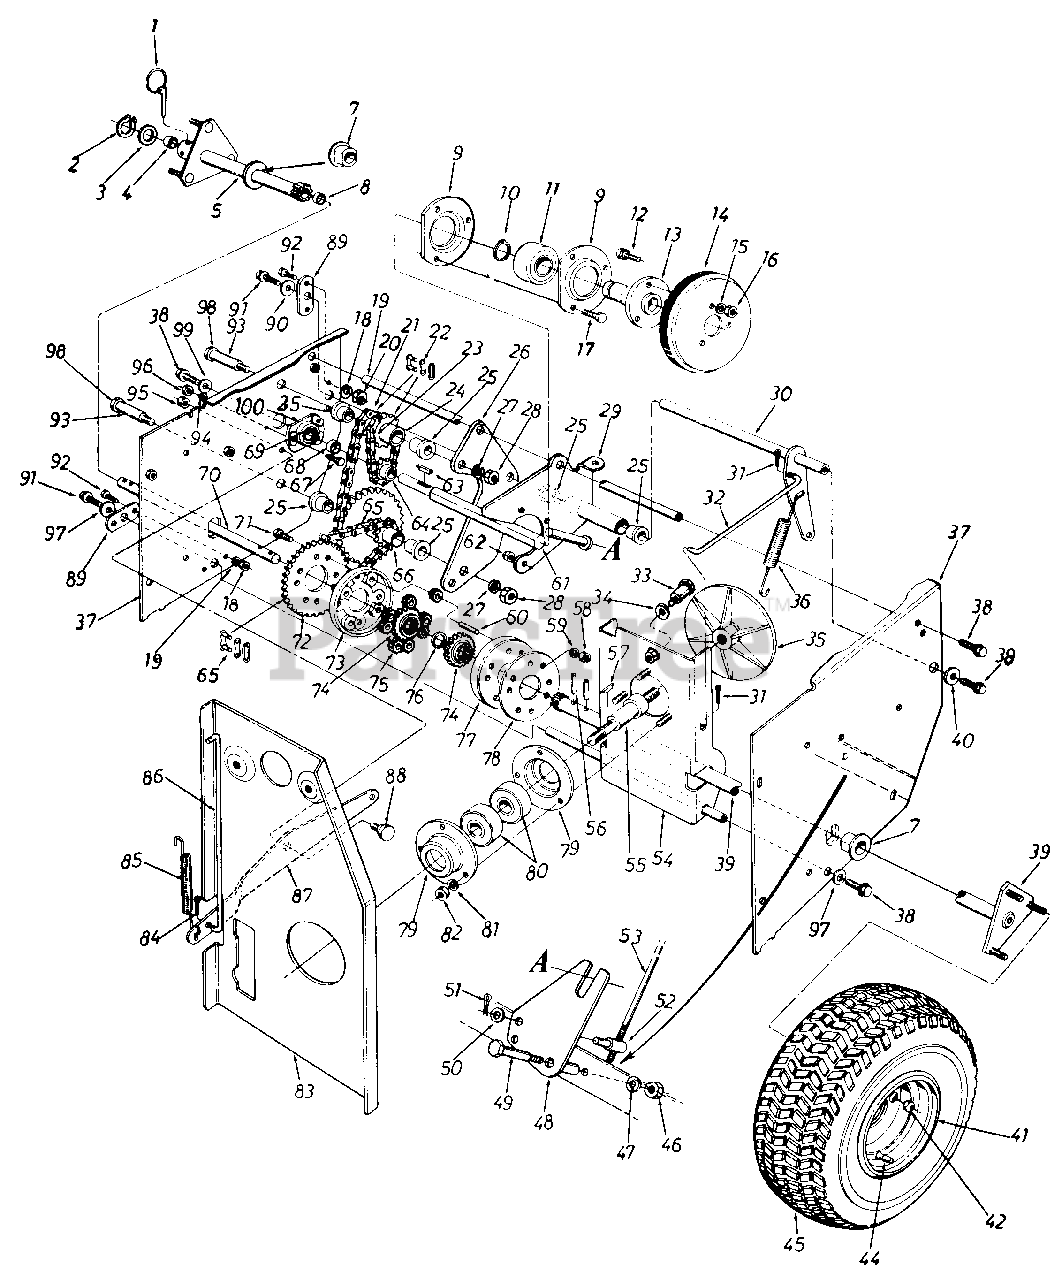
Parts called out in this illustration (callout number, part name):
1	Klick Pin 1/4 Dia. x 1.75
2	Snap Ring .625" Shaft
3	Fl-Wash. .62" I.D. x 1.25"
4	Sleeve Brg.
5	Differential Tubing Ass'y.
7	Flange Brg. w/Flats 1" I.D.
8	Sleeve Brg.
9	Bearing Housing
10	Snap Ring 1.00" Dia.
11	Ball Brg. .25MM x 52MM x 15MM Thk.
12	Hex Sems Bolt 5/16-18 x . 75 " Lg .
13	Friction Wheel Adapter
14	Friction Wheel Ass'y.
15	L-Wash. 5/16" I.D.
16	Hex Nut 5/16-18 Thd.
17	Hex Bolt 1/4-28 x .62" Lg.
18	L-Wash. 1/4" I.D.
19	Sliding Support Axle
20	Hex Nut 1/4-20 Thd.
21	#41 Chain 1/2" Pitch x 43 Links
22	Master Link
23	#41 Chain 1/2" Pitch x 19 Links
24	and 14 Teeth Sprocket Hub Ass'y.
25	Flange Brg. .630" I.D.
28	Hex L-Jam Nut 3/8-24 Thd.
29	Sliding Brkt. Ass'y.
30	Drive Clutch Brkt. Ass'y.
31	Inter. Cot. Pin 5/16" Dia.
32	Drive Clutch Rod 7.38" Lg.
33	Shld. Bolt
34	Bell-Wash. .44" I.D. x .88"
35	Aluminum Drive Plate
36	Extension Spring 4.31" Lg.
37	Frame Ass'y.
38	Hex L-Bolt 5/16-18 x .62"
39	Differential Shaft Ass'y.
40	Fl-Wash. .345" I.D. x .75"
41	Rim Only 16"
42	Cone Nut 3/8-24 Thd.
44	Tubeless Air Valve
45	Wheel Ass'y. Comp. 16 x 6.5
46	Jam Nut 3/8-16 Thd.
47	L-Wash. 3/8" I.D.
50	Fl-Wash. .344" I.D. x .62"
51	Cotter Pin 3/32" Dia. x .75"
52	Adjustment Ferrule
53	Shifting Rod
56	H-Spring Pin Spiral 3/16" Dia. x 1.25" Lg.
57	#61 Hi-Pro Key 3/16 x 5/8" Dia.
58	Hex Nut 1/4-28 Thd.
59	L-Wash. 1/4" I.D.
60	Differential Pin
61	Hex Shaft
62	Hex L-Nut 1/4-28 Thd.
63	#9 Hi-Pro Key 3/32 x 5/8" Dia.
64	8 Teeth Sprocket
65	#420 Chain .50 Pitch x 37 Links
66	9 and 32 Teeth Sprocket Hub Ass'y.
67	Hex Bolt 1/4-20 x .62" Lg.
68	Spacer .51" I.D. x .69" O.D.
69	Ball Bearing
70	Differential Connecting Shaft
71	Hex Bolt 1/4-28 x 1.75" Lg.
72	28 Teeth Sprocket
73	Differential Housing
74	20 Tooth Spur Gear
75	9 Tooth Spur Gear
76	Fl-Wash. .62" I.D. x 1.25"
77	Differential Housing
78	Differential Hsg. Support Plate
79	Bearing Housing
80	Ball Brg. .787" I.D. x 1.85"
81	L-Wash. 5/16" I.D.
82	Hex Nut 5/16-18 Thd.
83	Engine Brkt. Ass'y.
84	Inter. Cotter Pin 5/16" Dia.
85	Extension Spring 3.18" Lg.
86	Auger Clutch Rod .31" Dia. x 10.62" Lg.
87	Auger Clutch Brkt.
88	Shld. Bolt .625" Dia. x 170"
89	Pivot Axle Brkt.
90	Fl-Wash. .345" I.D. x .75"
91	Hex L-Bolt 5/16-18 x .62"
92	Hex Bolt 1/4-20 x .62" Lg.
93	Sprocket Hub Tubing 1.88"
94	L-Wash. 1/4" I.D.
95	Hex Cent. L-Nut 3/8-16 Thd.
96	Hex Nut 1/4-20 Thd.
97	Fl-Wash. .344" I.D. x .875"
98	Hex Bolt 3/8-24 x 2.75" Lg.
99	Bell-Wash. .345" I.D. x .88"
100	Bearing Housing
